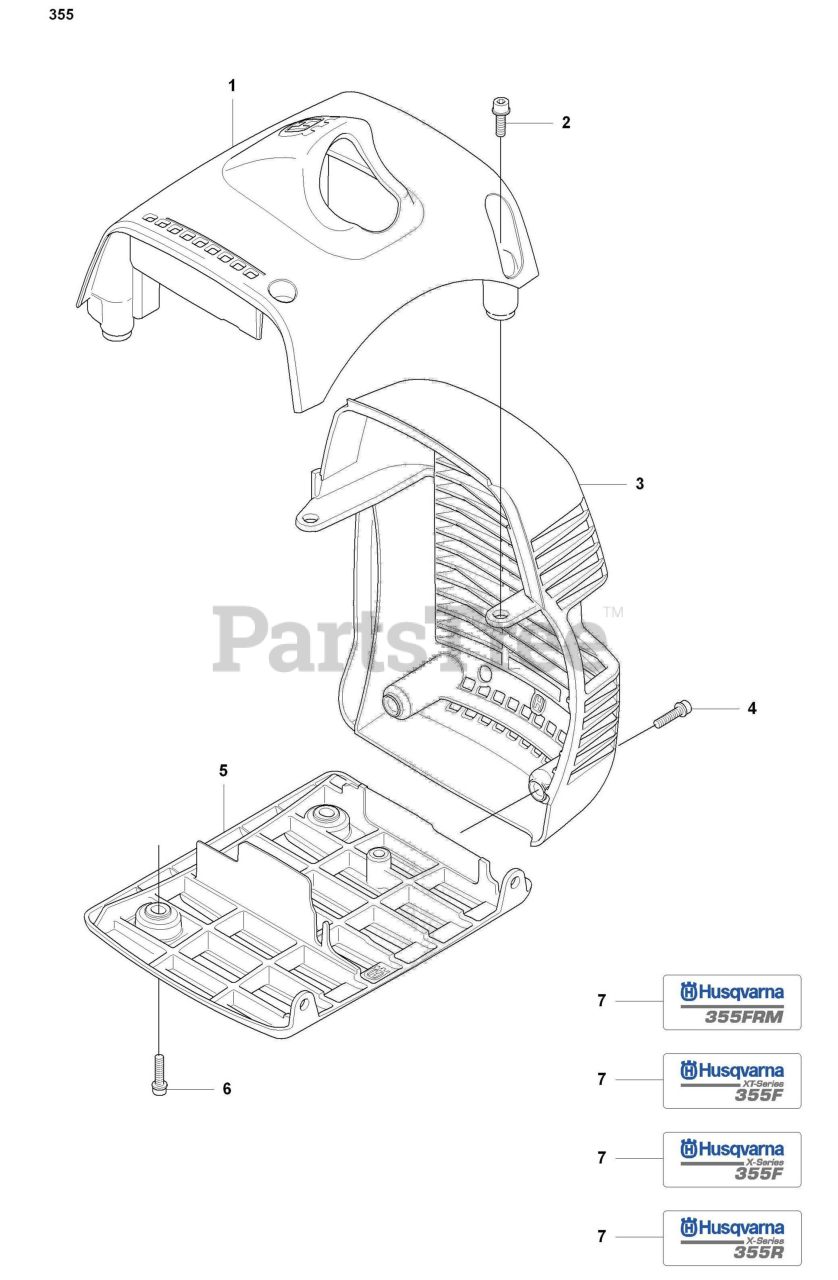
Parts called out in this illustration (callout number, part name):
1	CYLINDER COVER
3	HEAT PROTECTOR
5	PROTECTIVE COVER
7	LABEL
